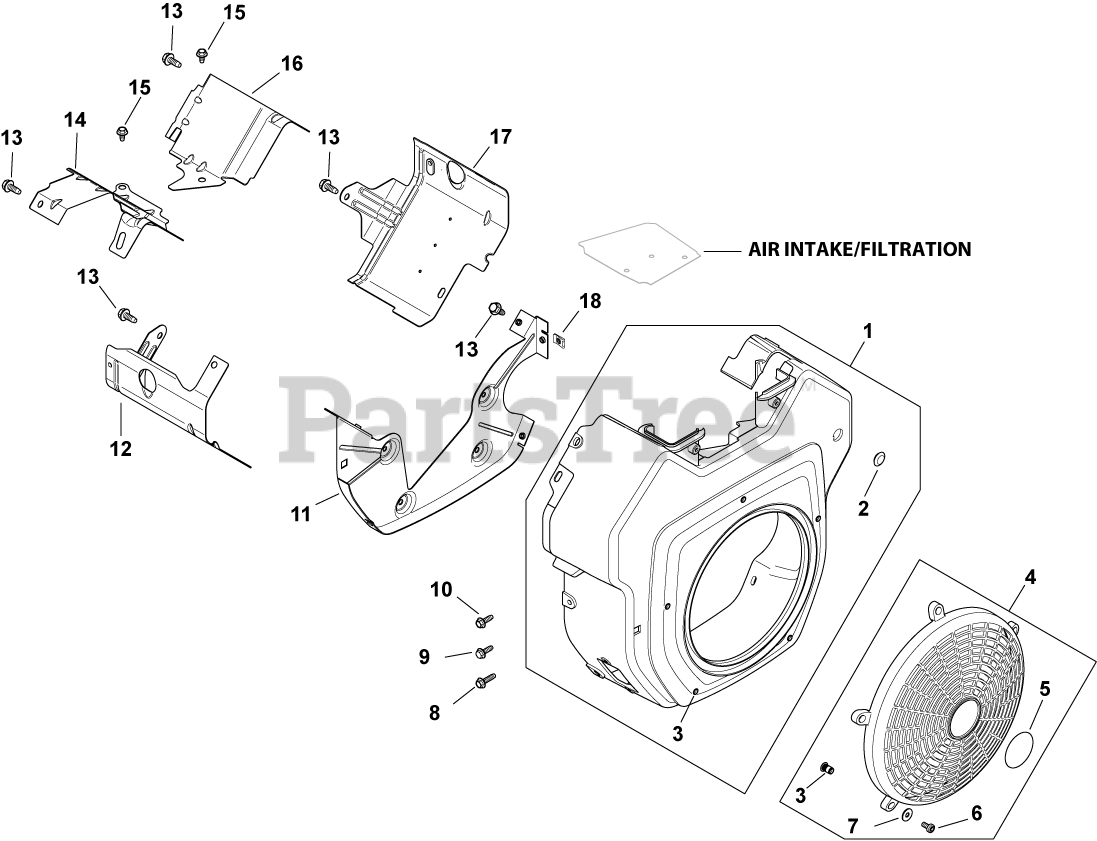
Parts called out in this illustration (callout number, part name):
2	NUT, PLASTIC (KM)-USE 25 100 37-S
3	INSERT, THREADED USE 25 332 19-S
4	KIT, FIXED GUARD
5	DECAL, GRASS SCREEN USE 24 113 499-S
6	SCREW, LBD SCKT PAN M5X0.8X10
7	WASHER, FLAT 7/32"
8	SCREW, FLG THD FRM M5X.8X20-(#25086399S)
9	SCREW - USE M-545016-S
10	SCREW,FLG THD FRM M5X0.8X16-(#25086398S)
11	PLATE, BACKING-USE 24 146 59-S
12	BAFFLE,VALLEY #2SIDE(KM)-USE 24 063 88-S
13	SCREW,FLG THD FRM M6X1.0X16-(#25086397S)
14	BAFFLE, VALLEY #2 SIDE-USE 24 063 94-S
15	SCREW, FLG THD FRM M5X.8X10
16	BAFFLE, VALLEY (CH)-USE 24 063 93-S
17	BAFFLE, RIGHT BARREL-USE 24 063 85-S
18	CLIP, REPAIR (SPEED NUT)
